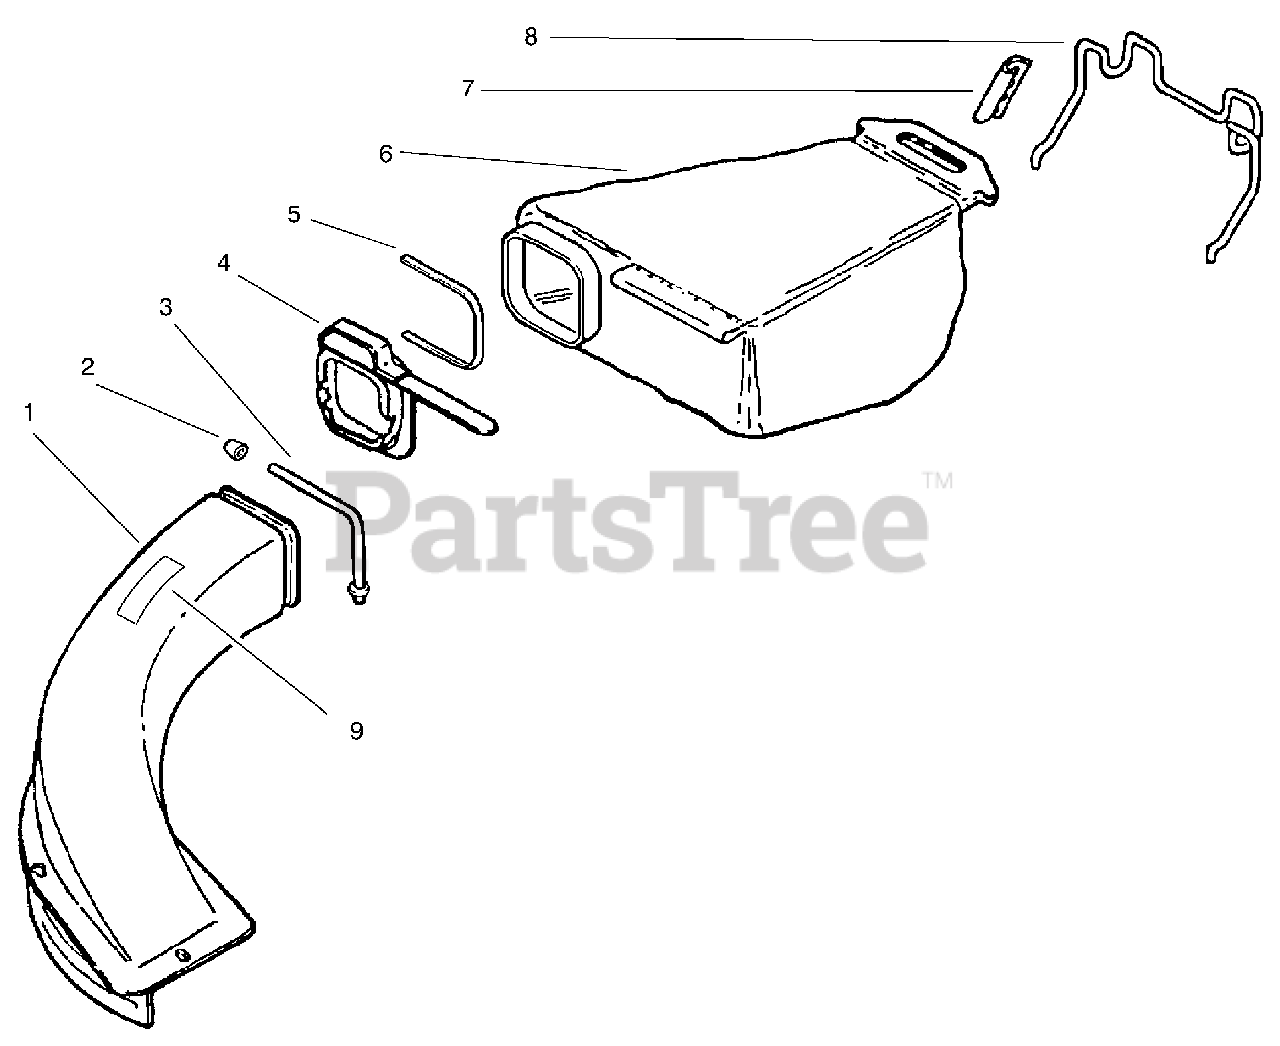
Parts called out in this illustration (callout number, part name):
1	ASM-Chute & Support
2	Nut-Cap
3	Chute Support
4	Adaptor Assembly
5	Tie Strap
6	ASM-Bag & Adapter
7	Hanger-Clamp
8	Hanger-Wire
9	Decal-Danger
